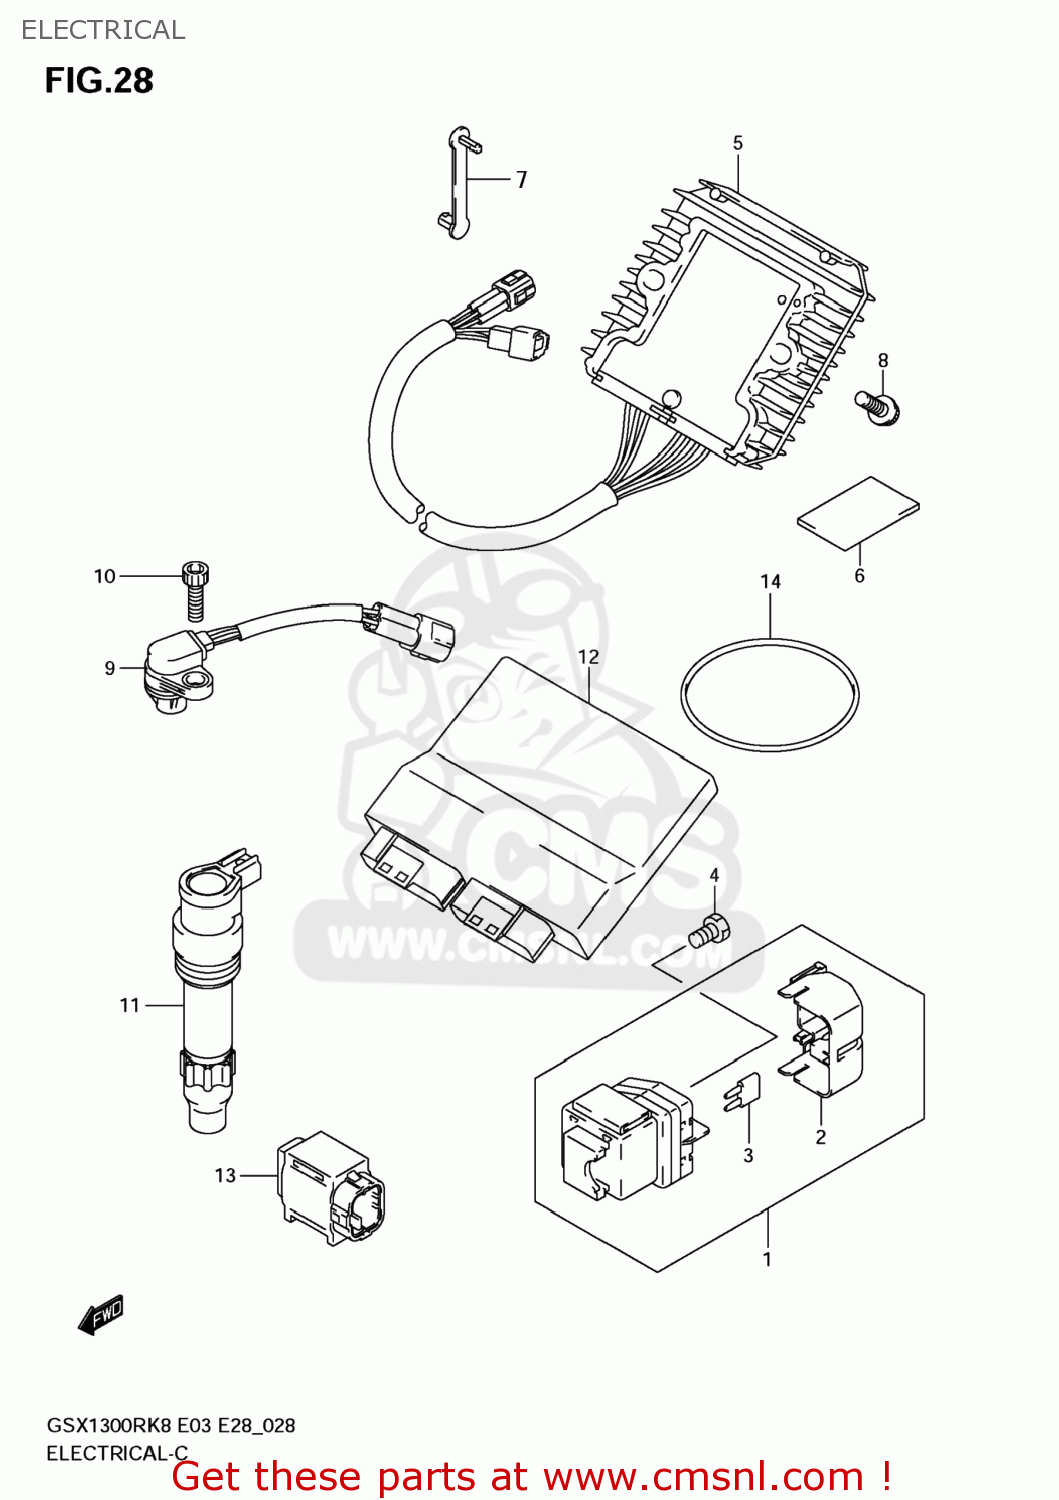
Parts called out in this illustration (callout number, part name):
1	RELAY ASSY,STARTING MOTOR
2	COVER
3	FUSE(30A)
4	SCREW(6X8)
5	RECTIFIER ASSY
6	CUSHION(30X50X3)
7	CLAMP(L:63)
8	SCREW
9	SENSOR ASSY,CAM POSITION
10	BOLT
11	COIL ASSY,IGNITION
12	CONTROL UNIT,FI
13	SENSOR ASSY,FUEL CUT
14	O RING(D:3.5,ID:76)
